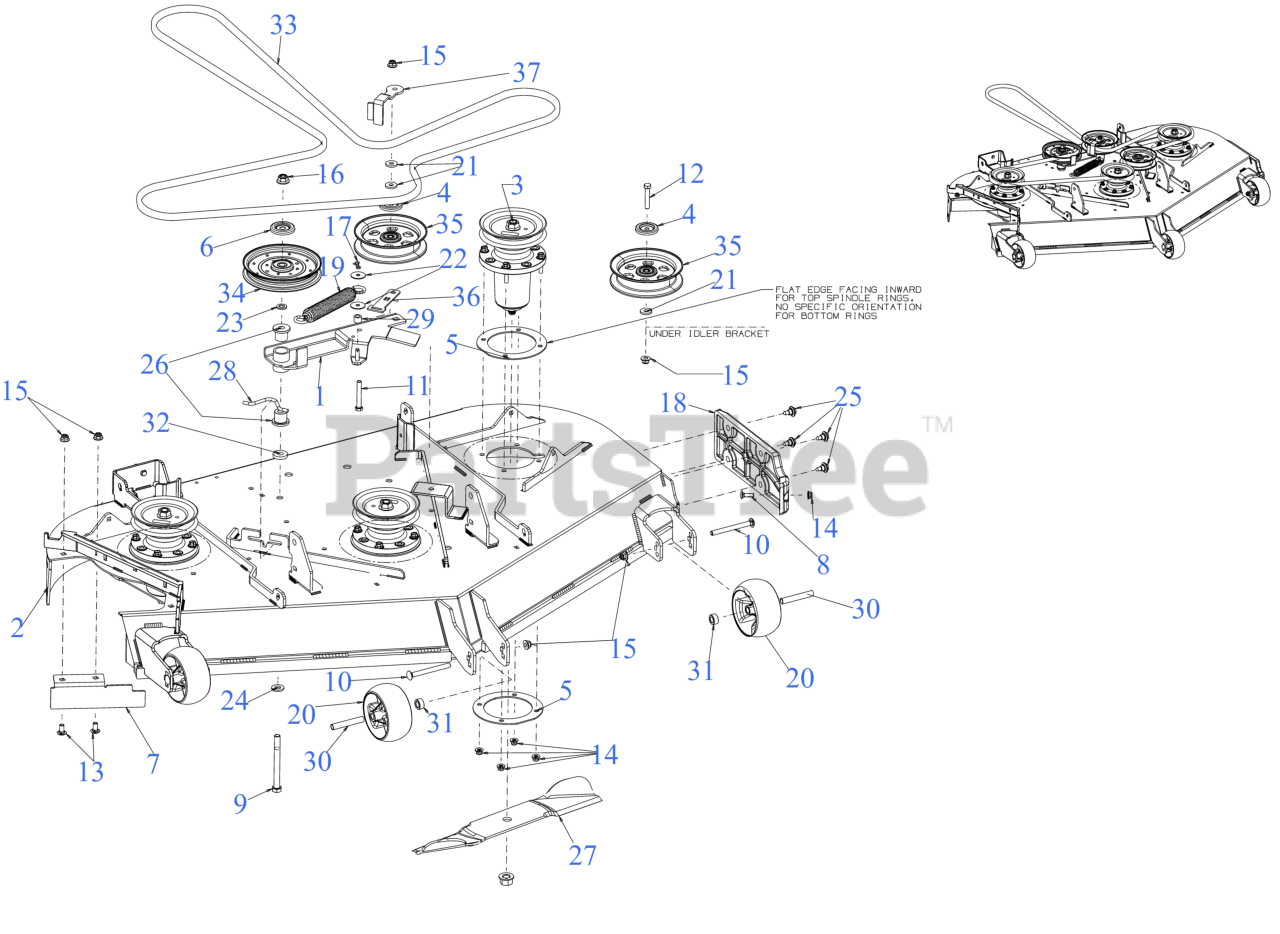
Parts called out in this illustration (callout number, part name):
1	54/60" DECK IDLER ASSEMBLY
2	54" FAB DECK SHELL
3	SPINDLE ASSEMBLY
3	Cub Cadet 54" SPINDLE ASSEMBLY (07416)
4	PULLEY CAP 1.875 DIA
5	SPINDLE PLATE
6	PULLEY CAP (.540 x 2.041 DIA)
7	BAFFLE
8	CARRIAGE BOLT 5/16-18 x 1.00
9	BOLT-HEX 1/2-13X5.0 GR5
10	CARRIAGE BOLT 3/8-16 x 4.00 GR5
11	HEX SCREW-3/8-16X2.5 GR5
12	SCREW 3/8-16 x 2.0 GR5
13	CARRIAGE BOLT 3/8-16 x .75
14	FLANGE LOCK NUT 5/16-18
17	BOW TIE COTTER PIN 1/4-5/16
18	DECK SKID PLATE
19	SPRING 1.25" DIA x 8.5" LONG
20	DECK WHEEL
20	WHEELS-DELUXE 5"
21	FLAT WASHER .385 x 1.00 x .135
22	FLAT WASHER .322 ID x 1.25 x .060
23	FLAT WASHER
24	FLAT WASHER .531X1.060X.134
25	SHOULDER SCREW .43X.29X5/16-18 TT
26	FLANGE BEARING
28	DECK SPRING HOOK
30	SPACER .38X.49X3.05LG
31	SPACER-.505 1D
32	SPACER PLATE
33	V-BELT B SEC x 148.25
33	Cub Cadet 54" DECK DRIVE BELT
34	IDLER PULLEY 6.0" DIA
35	5" FLAT IDLER PULLEY
36	BELT KEEPER
37	54/60" IDLER KEEPER
